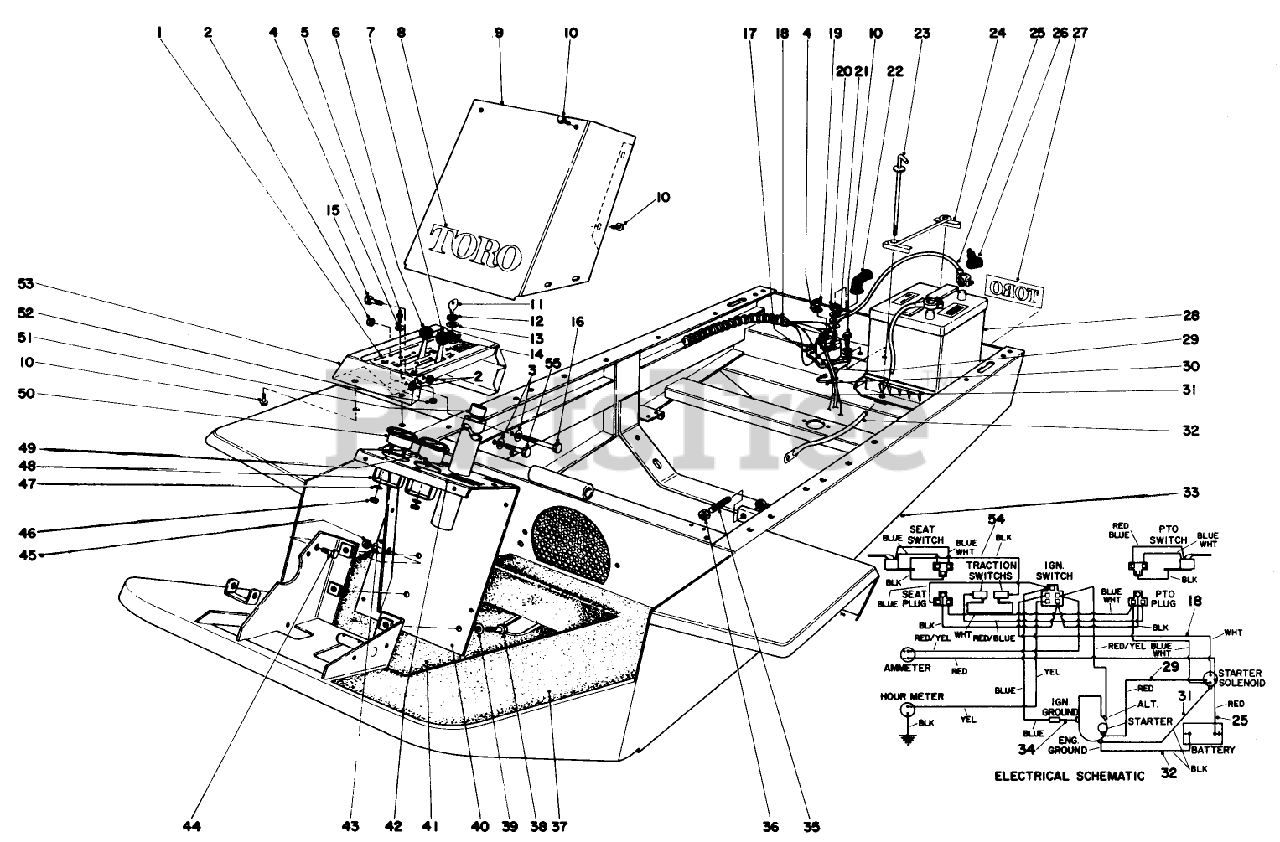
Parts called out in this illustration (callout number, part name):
1	Decal-Instrument Panel
2	NUT-HEX
3	WASHER-LOCK
4	WASHER-LOCK
5	10-24 X 5/8 PAN HD MS
6	CHOKE CONTROL
7	Throttle Control
8	DECAL
9	Cover-Tower
10	SCREW-THD FRM,HWH
11	Key
12	NUT-HH
13	WASHER-TOOTH, INTERNAL
14	SWITCH-STARTER
15	SCREW-HH
16	SCREW-HH
17	SOLENOID
18	Wire Harness
19	NUT-HEX
20	NUT-JAM, BRASS
21	WASHER-LOCK
22	BATTERY BOOT
23	BATTERY BOLT WA B
24	BATTERY HOLD DOWN WA
25	Wire Positive Batter to Solenoid
26	BOOT-CABLE, BATTERY
27	DECAL
28	Battery
29	SOLENOID TO START WIR
30	TIE-CABLE
31	Wire Engine Ground
32	BATTERY GROUND WIRE
33	Frame
34	ENGINE GROUND WIRE
35	STOP PIN PP
36	NUT-JAM
37	NON SKID (TUNNEL)
38	SCREW-HH
39	WASHER-LOCK
40	Steering Post Bracket (Incl. Ref. #51)
41	NON-SKID-FLOOR
42	Decal Instruction
43	WASHER-LOCK
44	SCREW-HH
45	NUT-HEX
46	Nut
47	Lockwasher
48	CLAMP ASM
49	HOUR METER
50	Ammeter
51	Bushing
52	NUT-HEX
53	Instrument Panel
54	Wire Traction Switch Ground
55	SCREW-HH
